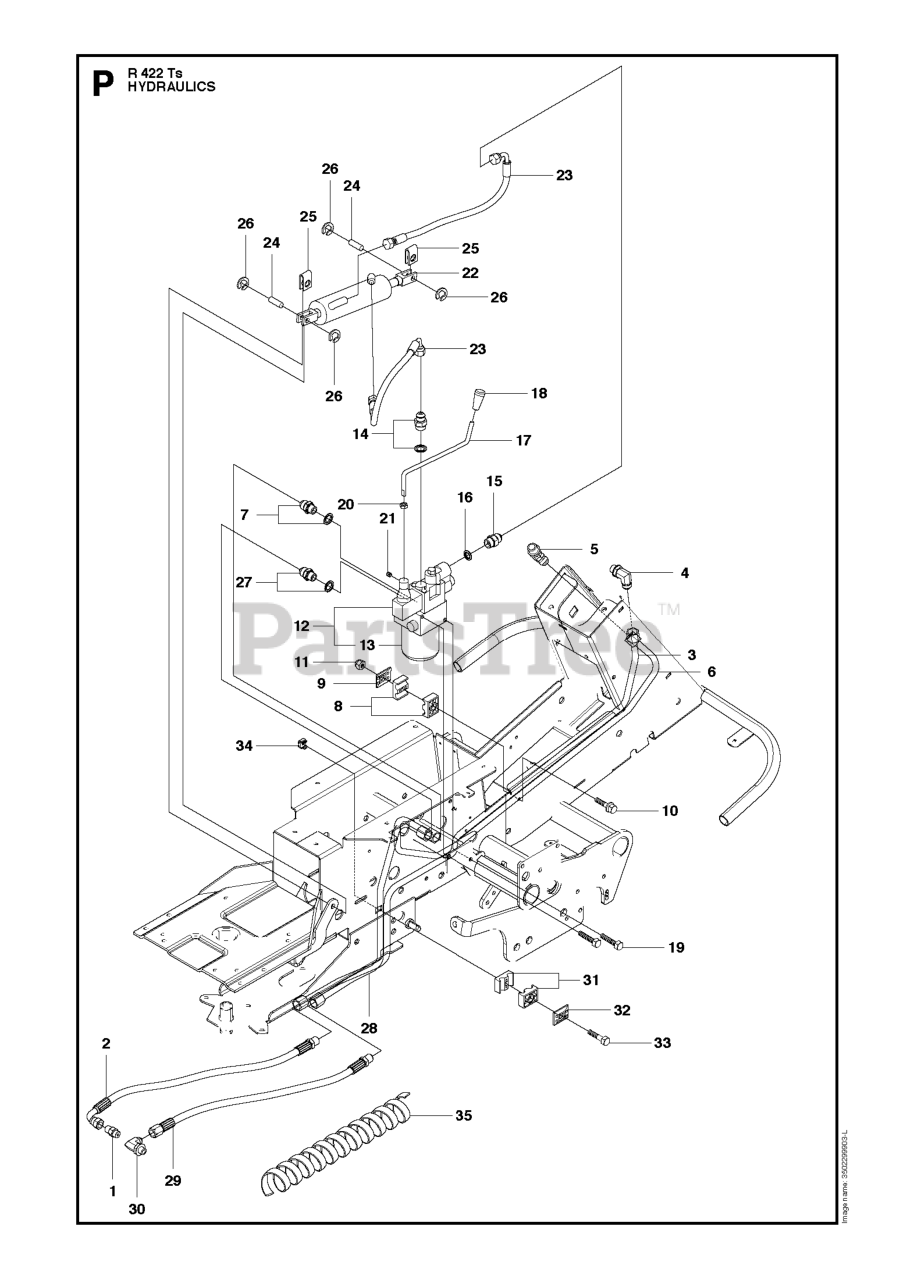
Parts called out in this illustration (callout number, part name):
8	PIPE CLAMP
11	LOCKNUT M6
13	FILTER
19	REPL BY 725 24 49-51
20	NUT
26	RETAINING RING SGA 10
31	PIPE CLAMP
